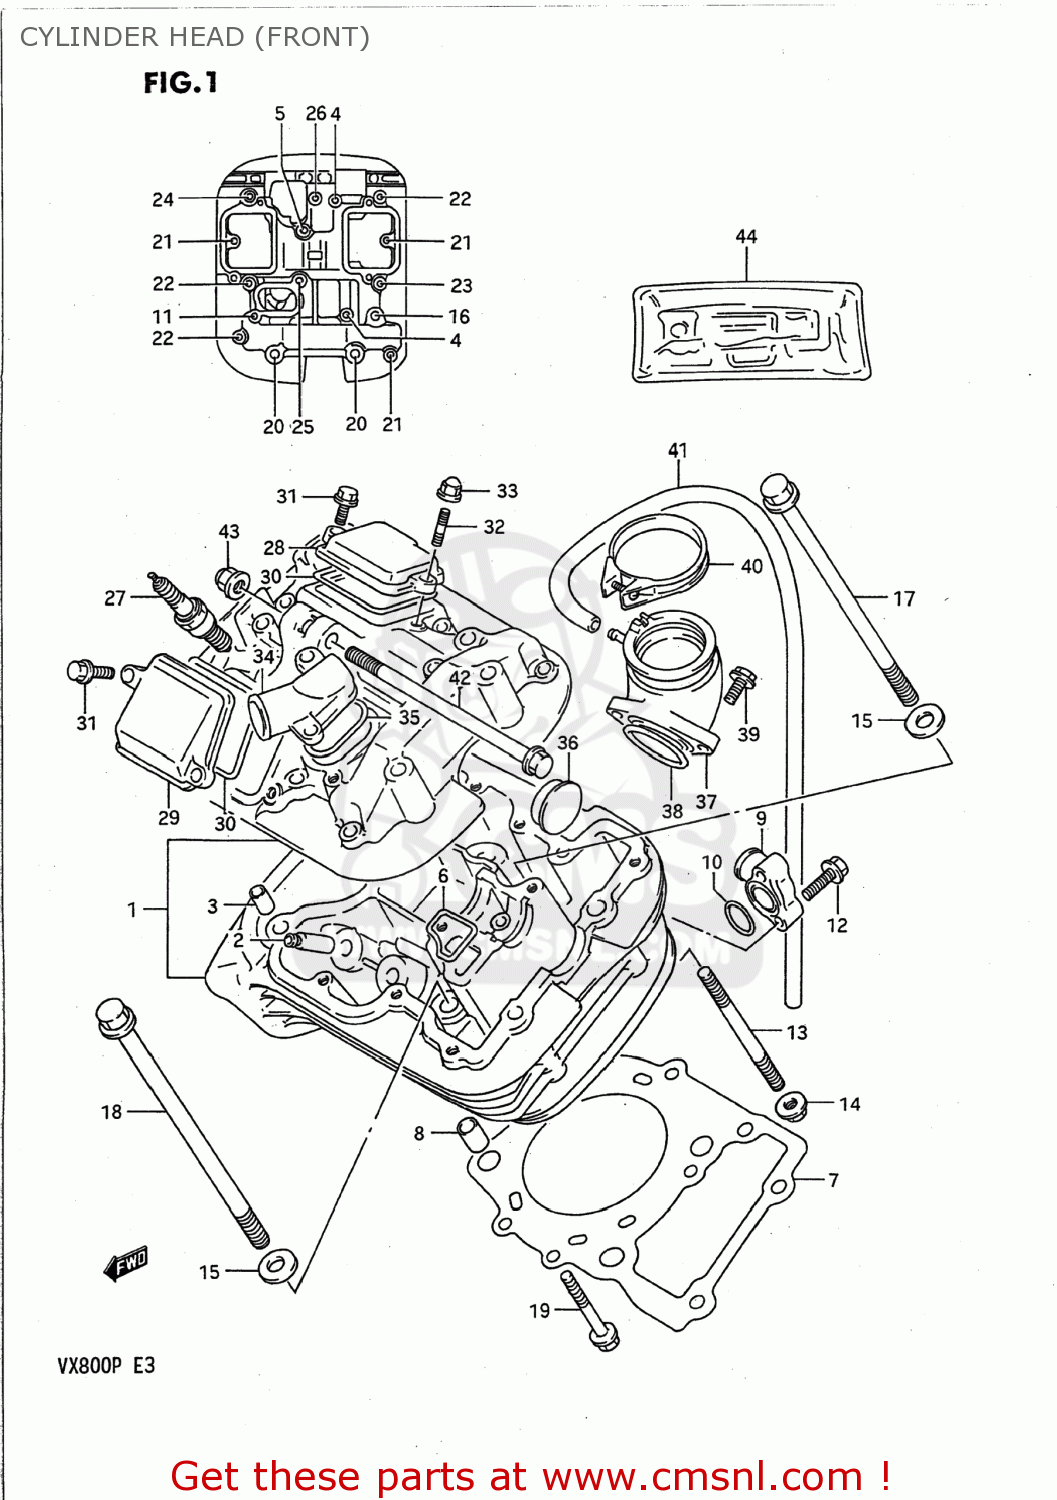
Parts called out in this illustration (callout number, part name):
1	HEAD ASSY,CYLINDER FRONT
2	GUIDE,VALVE
3	PIN(11X14)
4	BOLT(6X50)
5	BOLT(6X55)
6	GASKET,CYLINDER HEAD WATER (NAS)
7	GASKET,CYLINDER HEAD FR (NAS)
8	PIN
9	UNION,CYLINDER HEAD WATER
10	O RING(D:2.4,ID:17.8)
11	BOLT 6X20
12	BOLT
13	BOLT,STUD
14	NUT
15	WASHER(10.5X22X2.3)
16	BOLT(8X140)
17	BOLT(10X155)
18	BOLT(10X165)
19	BOLT
20	BOLT
21	BOLT 6X25
22	BOLT
23	BOLT
24	BOLT
25	BOLT(6X55)
26	BOLT(6X50)
27	PLUG,SPARK(DPR8EA-9)
28	CAP,INSP.INT
29	CAP,INSPECTION,EXHAUST
30	GASKET,INSPECTION CAP (NAS)
31	BOLT
32	STUD 6X16
33	NUT
34	UNION,WATER OUTLET
35	GASKET,WATER OUTLET UNION (NAS)
36	PLUG(OD:30)
37	PIPE,INTAKE
38	O-RING (D:2.4 ID:39.7)
39	BOLT
40	CLAMP,PIPE
41	HOSE
42	BOLT,ENGINE MOUNTING (8X150)
43	NUT (8MM)
44	GASKET SET (NAS)
